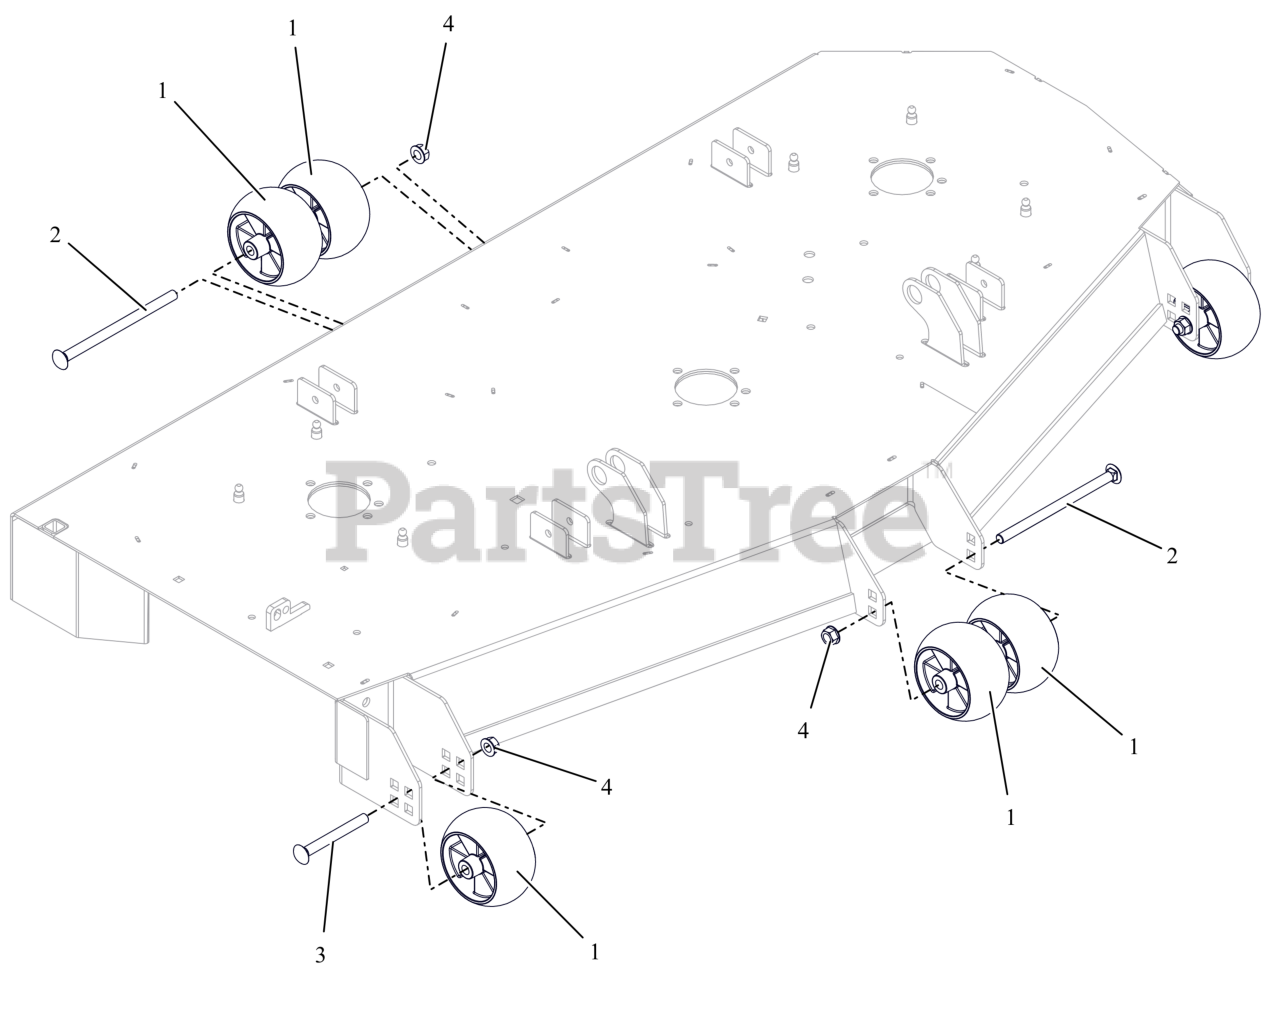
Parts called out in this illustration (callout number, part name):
1	WHEEL, ANTI SCALP - 5X3 CTR W/RIBS
2	BLT,RHSN .50-13X8.00 G5 ZCC NS
3	BLT,RHNS .50-13X4.50 G5 ZCC NS
4	NUT-LK-CTR-FLG .500-13 GG ZCC
